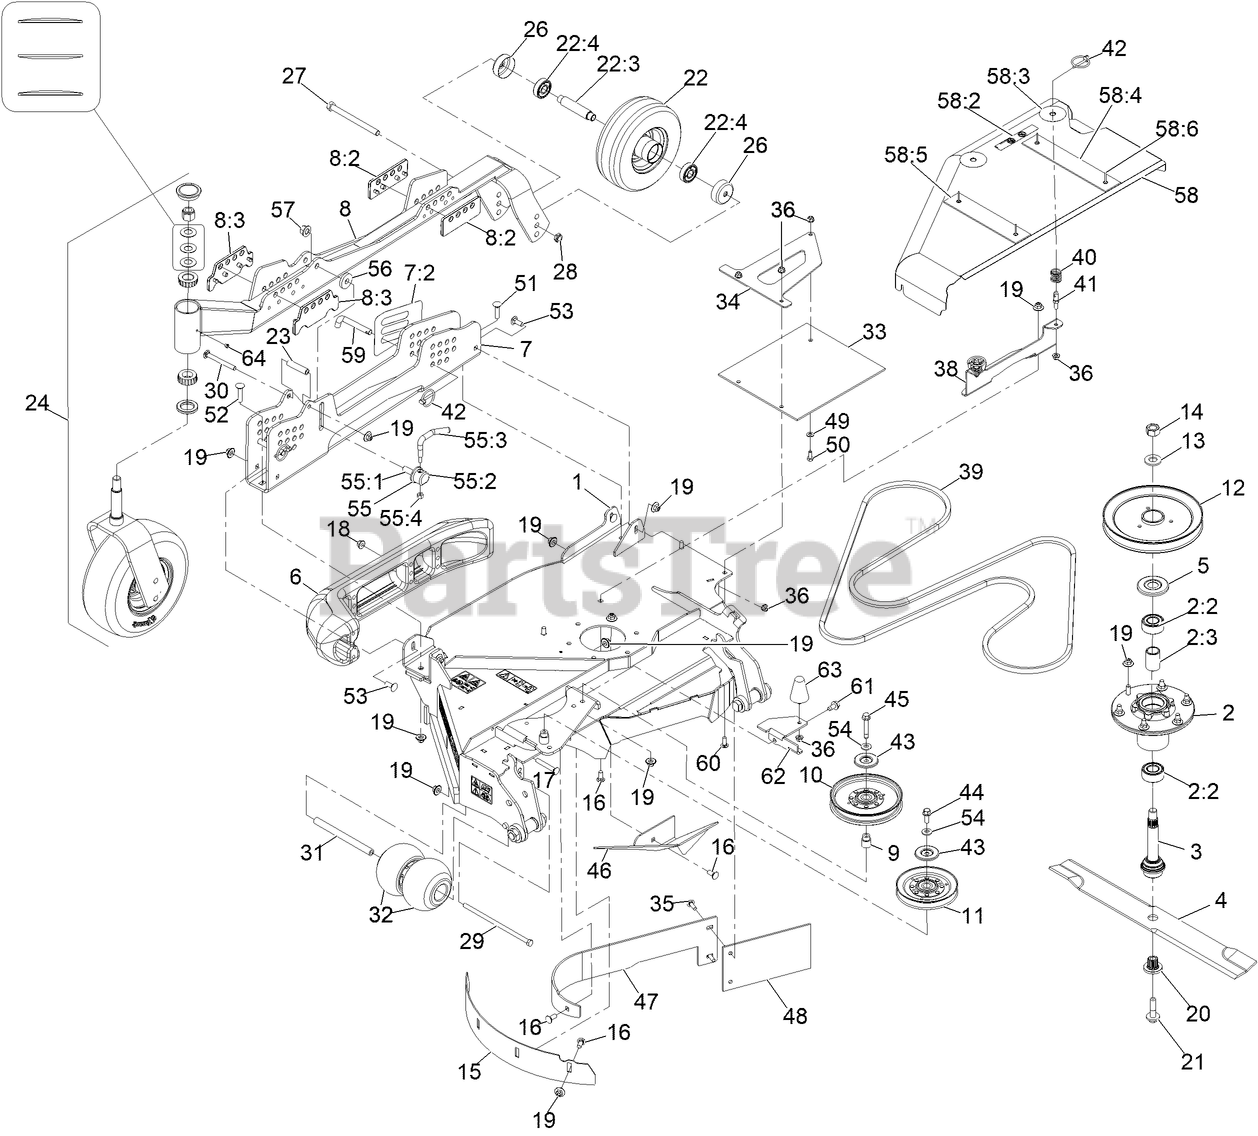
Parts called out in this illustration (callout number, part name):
1	ASM-DECK, RH WING 96E
2	ASM-CUTTER HSG
2:2	BEARING-3205 TRASHGUARD
2:3	SPACER-BEARING
3	ASM-SPINDLE AND SEAL
5	GUARD-BEARING, TOP
6	SKID-BUMPER, DECK
7	ASM-CHANNEL, HOC RH W/DECALS
7:2	DECAL-HEIGHT OF CUT-RH
8	ASM-RH GAUGE WHEEL ARM
8:2	PLATE-GUIDE, REAR
8:3	PLATE-GUIDE, FRONT
9	BUSHING-IDLER
10	IDLER-PULLEY
11	IDLER-V
12	SHEAVE-SINGLE 96RD
14	NUT-HEX
15	BAFFLE-DEPTH, RH
16	BOLT-CARR
17	SCREW-CARR
18	NUT-HF, NI
19	Nut-Nyloc 3/8-16 Flg
20	BUSHING,SPLINED
21	SCREW,SEMS 1/2-20 X 2.19
22	WHEEL AND TIRE ASM
22:3	AXLE-CASTER
22:4	BEARING
26	GUARD, SEAL
27	SCREW-HH
28	NUT-HEX
29	SCREW-HH
30	SCREW-CARR
31	SPACER-WHEEL
32	ROLLER-SCALP, ANTI
33	GUARD-TIRE
34	SUPPORT-FLAP, RH
35	SCREW-CARR
36	NUT-HF, NI
38	BRACKET-SHIELD MOUNT, OUT
41	PIN, SPRING
42	PIN-LYNCH
43	SHIELD-DUST
44	SCREW-HHF 3/8-16 X 1
45	SCREW-HHF
46	BAFFLE-DEFLECT, RH
47	BAFFLE-DOGLEG, RH
48	FLAP-RUBBER
49	WASHER-PLAIN
50	SCREW-HH
51	SCREW-CARR
52	SCREW-CARR
53	BOLT-CARR
54	WASHER-BELLEVILLE
55	LEVER ASM
55:1	SCREW-LOCK
55:2	CAP-LOCK
55:4	NUT-LOCK, NI
57	Nut-Lock 1/2-13
58	ASM-Wing Shield RH
58:2	DECAL-NO STEP
58:3	DECAL-SCRATCH COVER
58:4	Plate-Uhmw 2"
58:5	PLATE-FRONT
58:6	Rivet-Pop
59	PIN-HOC
60	BOLT-CARR
61	SCREW-HWH
62	BRACKET-COVER RETAINER
63	BUMPER-RUBBER
